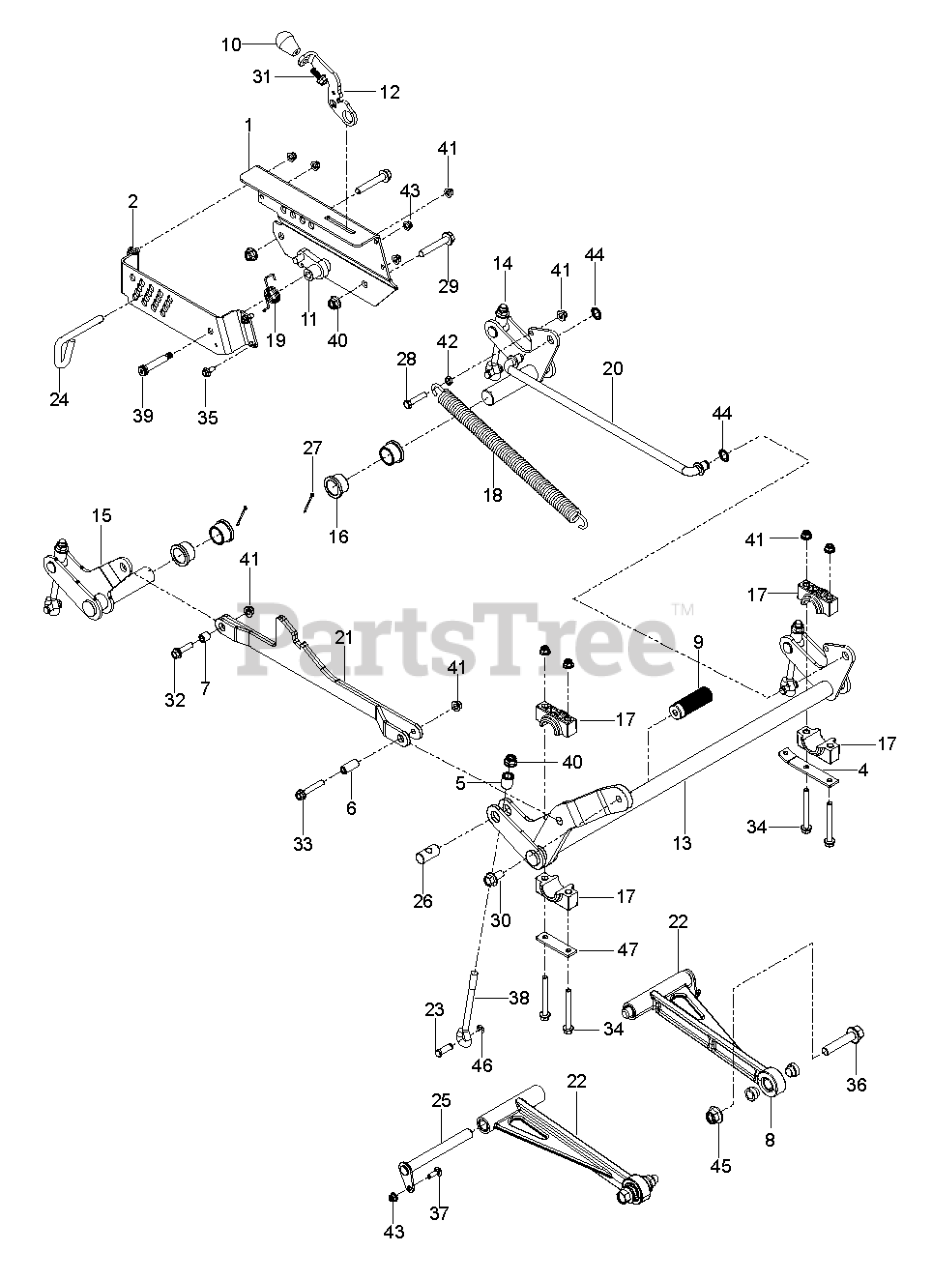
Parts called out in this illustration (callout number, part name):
1	PLATE HEIGHT SNAPPER RED X672
2	PLATE HEIGHT SNAPPER RED X672
4	PLATE, SPRING ANCHOR
5	SPACER, EYEBOLT
6	SPACER, FRONT LIFT STRAP
7	SPACER, REAR LIFT STRAP
8	SPACER, STRUT
9	PEDAL, DECK HEIGHT
10	KNOB - SHIFT
11	LATCH, TRANSPORT WLDMT
12	LEVER, TRANSPORT RELEASE
13	SHAFT DECK LIFT FT
14	SHAFT, LIFT LEFT REAR
15	SHAFT, LIFT RIGHT REAR
16	BUSHING, FLANGE 1.25 X 1.0
17	BLOCK, PILLOW
18	SPRING, EXTENSION
19	SPRING, TORSION
20	ROD, LIFT
21	WELDMT, DECK STRAP
22	ASSEMBLY, STRUT
23	PIN, 7/16 CLEVIS
24	PIN, HEIGHT
25	PIN, STRUT
26	PIN, TRUNION, EYEBOLT
27	COTTER PIN 1/8 X 2
28	HCS 3/8-16 X 1 3/4 GR5
29	HFFS 1/2-13 X 3 GD 5 ZD
30	HHFS 1/2-13 X 1 GR5 ZD
31	HHFS 3/8-16 X 1 GRD 5 ZD
32	HHFS 3/8-16 X 1.50 GR5 ZD
33	HHFS 3/8-16 X 2-1/4 GR 5 ZD
34	HHFS 3/8-16 X 3.5 GD 5 ZD
35	HHFS 5/16-18 X 3/4
36	HHFS 5/8-11 X 3.0 GD 8 ZD
37	RHSNB 5/16C X 1
38	EYEBOLT, DECK LIFT
39	BOLT, SHOULDER, 1/2 X 2.25
40	NUT, 1/2-13 HEX FLG NYLOC ZD
41	NUT 3/8-16 HEX FLG NYLOC ZD
42	NUT 3/8-16 HEX JAM
43	5/16-18 NYLOC FLANGE NUT
44	NUT.PUSH.625
45	NUT 5/8-11 FLG NYLOC ZD
46	RING, E, 7/16
47	PLATE.PNT.PILLOW.BLOCK.EDIP
